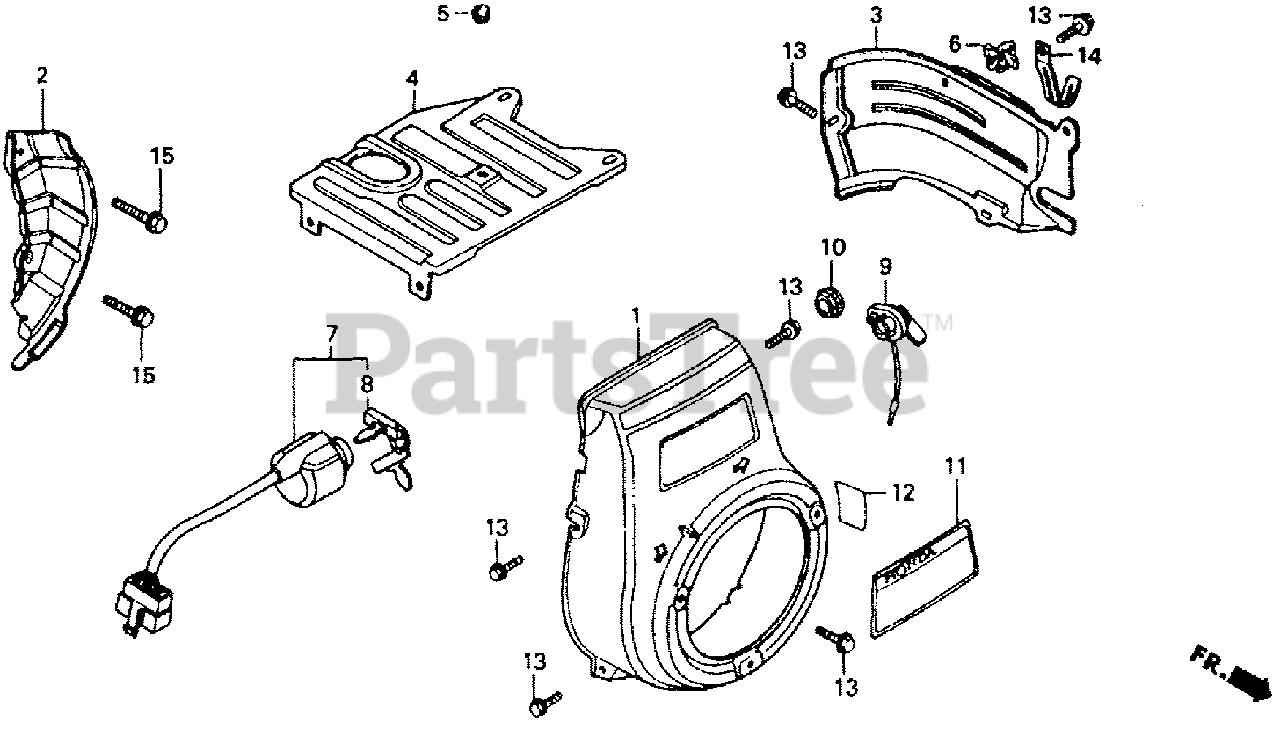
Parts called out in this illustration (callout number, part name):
1	COVER, FAN *R8* (BRIGHT RED)
2	PLATE, SIDE
3	SHROUD *R8* (BRIGHT RED)
4	COVER, TOP *R8* (BRIGHT RED)
5	GROMMET, TOP COVER
6	CLIP, IGNITION WIRE (8MM)
7	SWITCH ASSY., COMBINATION
8	KEY
9	SWITCH ASSY., ENGINE STOP
11	EMBLEM (ENGLISH/FRENCH/SPANISH)
12	MARK, OIL CAUTION
13	BOLT, FLANGE (6X12) (CT200)
14	CLIP, WIRE HARNESS
15	BOLT, FLANGE (8X20)
